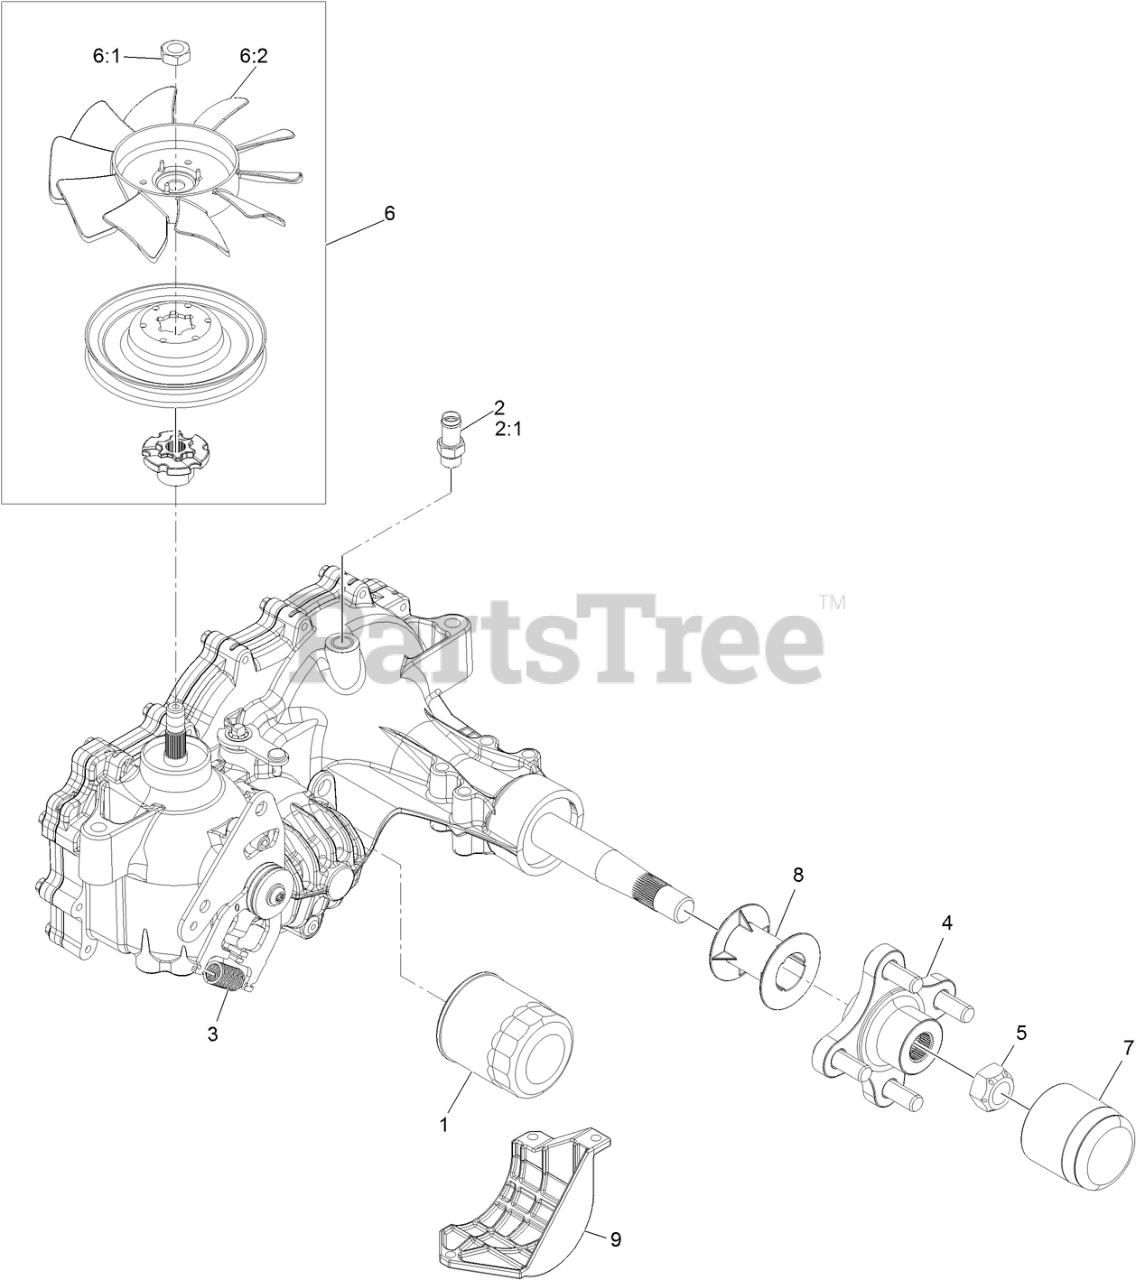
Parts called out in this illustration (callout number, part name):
1	ELEMENT-OIL FILTER, HYD
2	ADAPTER-STRAIGHT
2:1	O-RING
3	SPRING-EXTENSION
4	HUB-OFFSET
5	NUT-HUB
6	Fan And Pulley Kit
7	CAP-AXLE, LONG
8	TUBE-AXLE
9	GUARD-FILTER, LH
